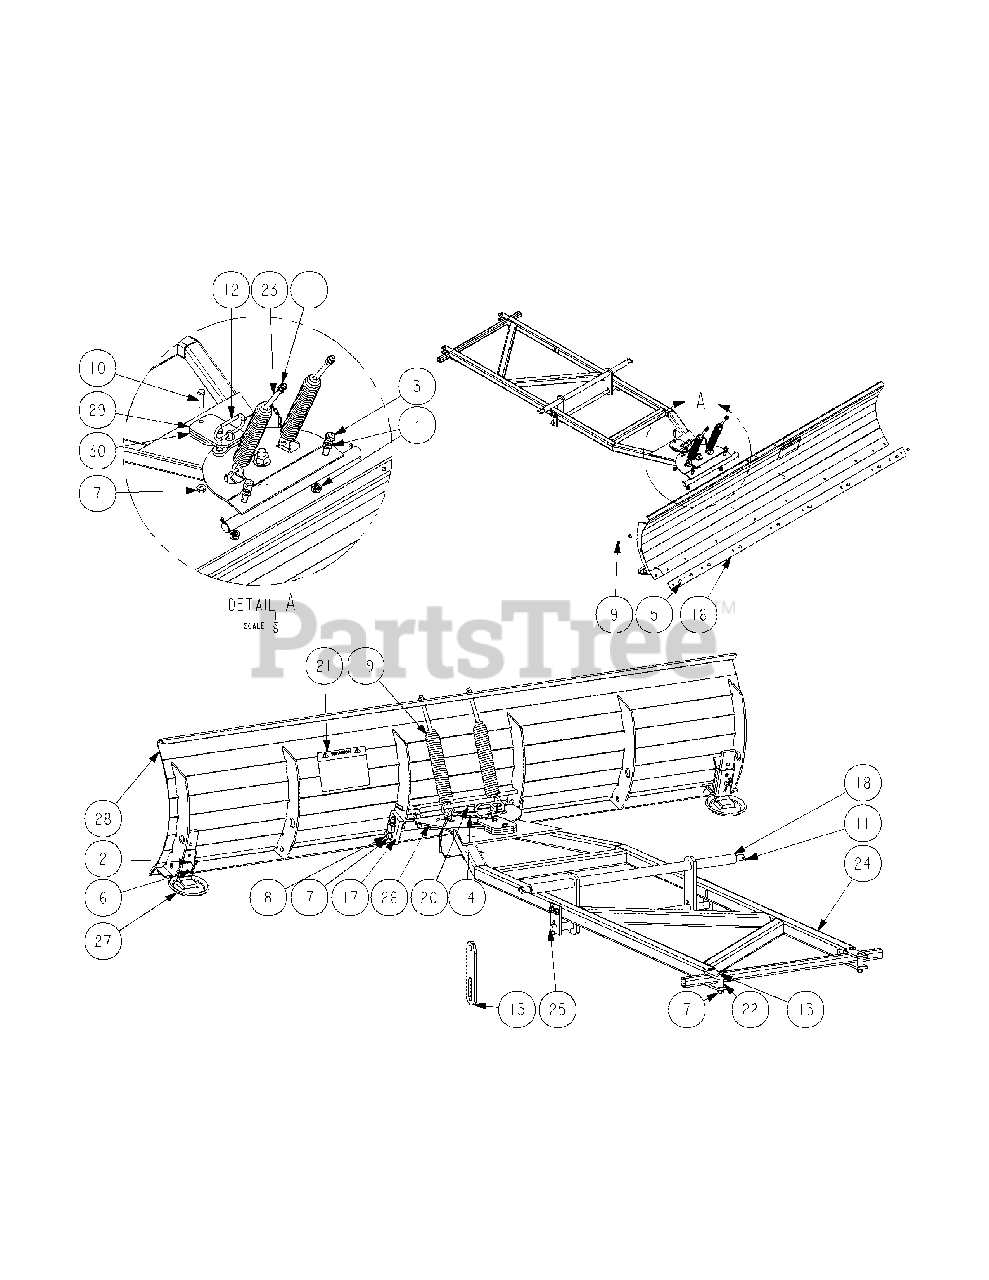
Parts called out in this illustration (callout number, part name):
1	Hex Nut 3/8-16
2	Clevis Pin, 3/8 x 1-1/8 Zinc
3	Hex Cap Screw:1/2-13 x 2.0
4	Hex Nut:1/2-13
5	Carriage Bolt:5/16-18 x .75
6	Hair Pin, 3/8-1/2
7	Flange Lock Hex Nut, 3/8-16
8	Hex Cap Screw, 3/8 -16 x 1.25
9	Hex Flange Lock Nut, 5/16-18
10	Hex Cap Screw, 3/8-16 x 1-1/2
11	Cotter Pin, 5/32, 1.25
12	Sulky Pin
13	Hex Cap Screw:3/8-16 x 2.0
14	Nut, 3/4-16, Hex Flange
15	Deck Lift Link
17	Rod Bearing Pivot Plate
20	Hex Cap Screw, 3/4-16 x 3.00
21	Label, Warning
22	Rear Support Spacer
23	Bolt:3/8-16 x 4.50
30	Plow Spacer
